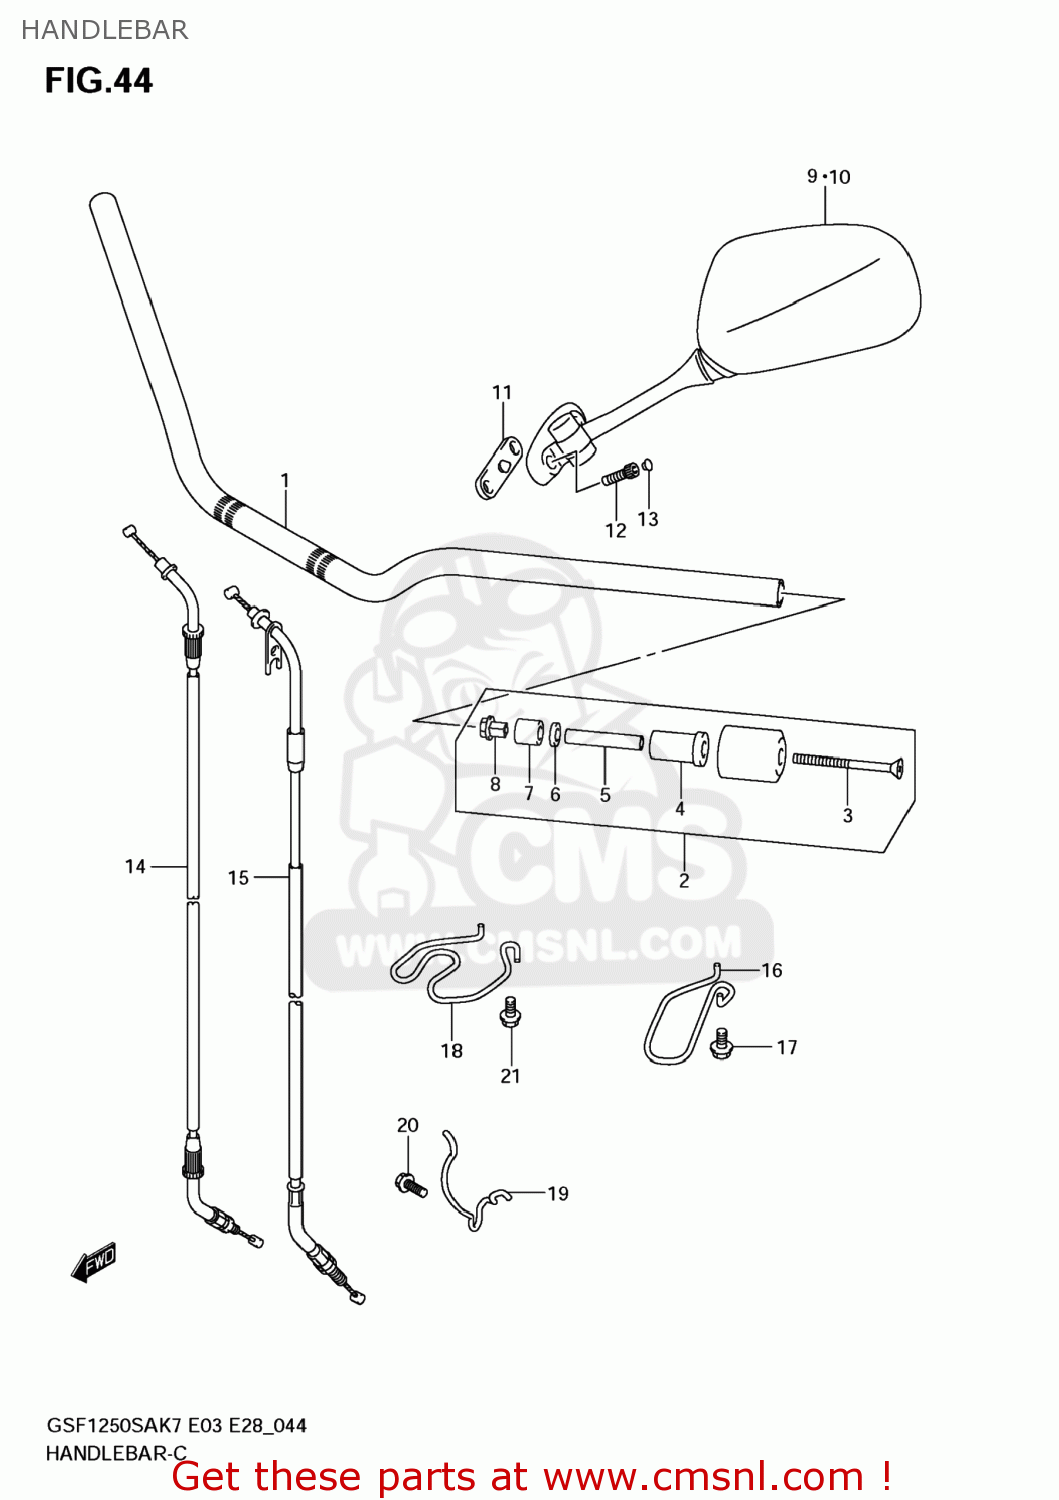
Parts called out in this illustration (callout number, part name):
1	HANDLEBAR
2	BALANCER SET,HANDLEBAR
3	SCREW(6X110)
4	EXPANDER,HANDLE BALANCER
5	SPACER,EXPANDER
6	WASHER(6.5X16X4)
7	EXPANDER,HANDLE BALANCER
8	NUT,HANDLE BALANCER
9	MIRROR ASSY,RR VIEW,R
10	MIRROR ASSY,RR VIEW,L
11	CUSHION,RR VIEW MIRRORR
12	BOLT
13	CAP(OD:10)
14	CABLE ASSY,THROTTLE NO.1
15	CABLE ASSY,THROTTLE NO.2
16	GUIDE,THROTTLE CABLE NO.2
17	SCREW(5X10)
18	GUIDE,THROTTLE CABLE
19	GUIDE,CABLE,R
20	BOLT
21	BOLT
